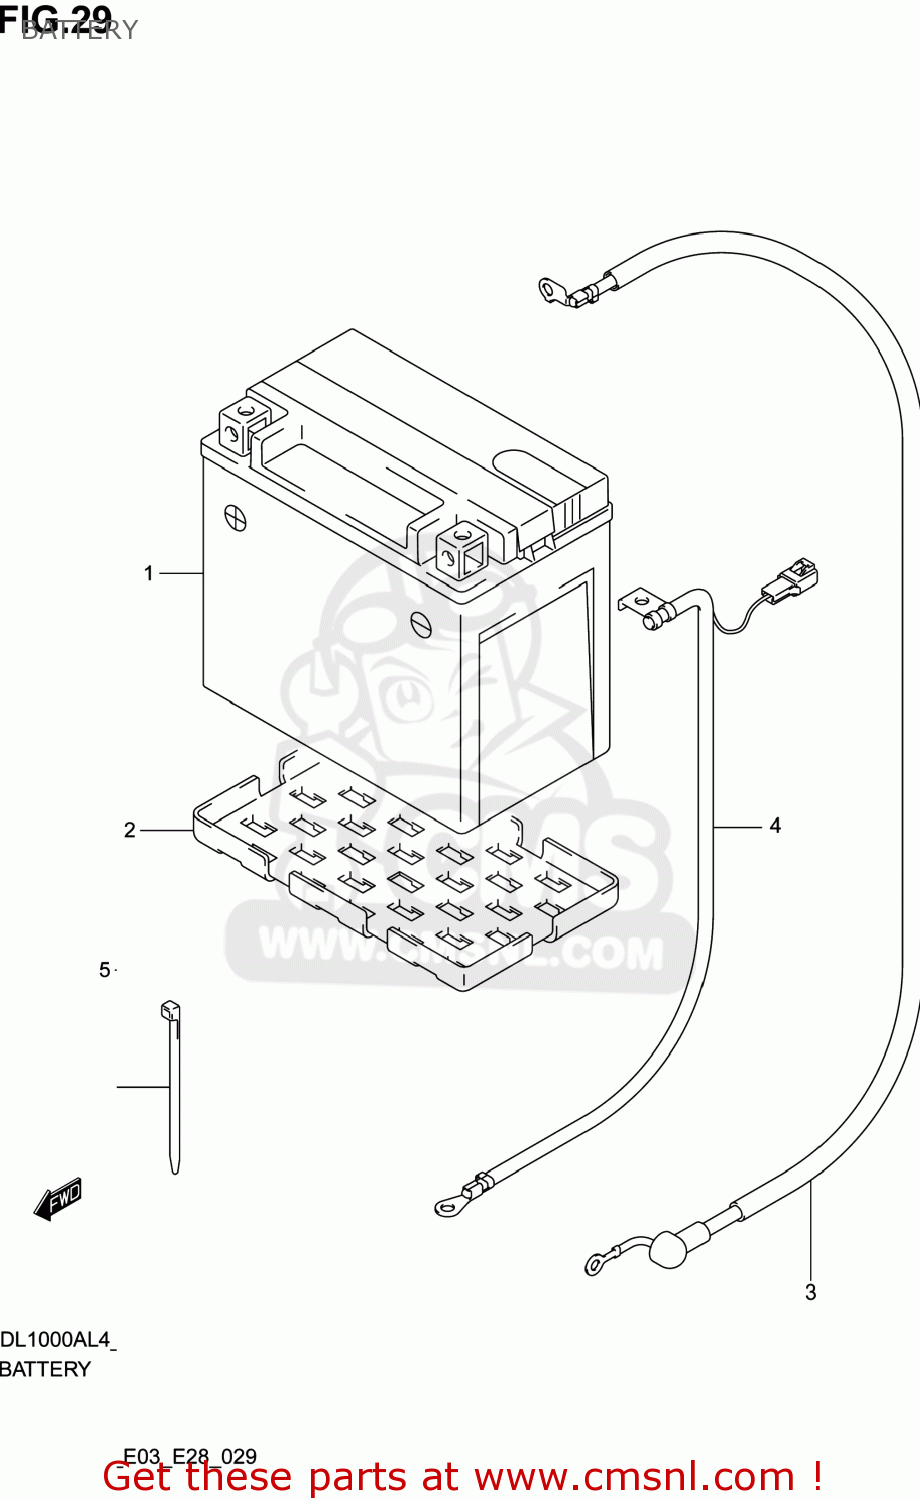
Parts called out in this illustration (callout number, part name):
1	BATTERY ASSY (12V) YTX14-BS
2	PROTECTOR,BATTERY
3	WIRE,STARTER MOTOR LEAD
4	WIRE,BATTERY MINUS LEAD
5	CLAMP(L:145)
